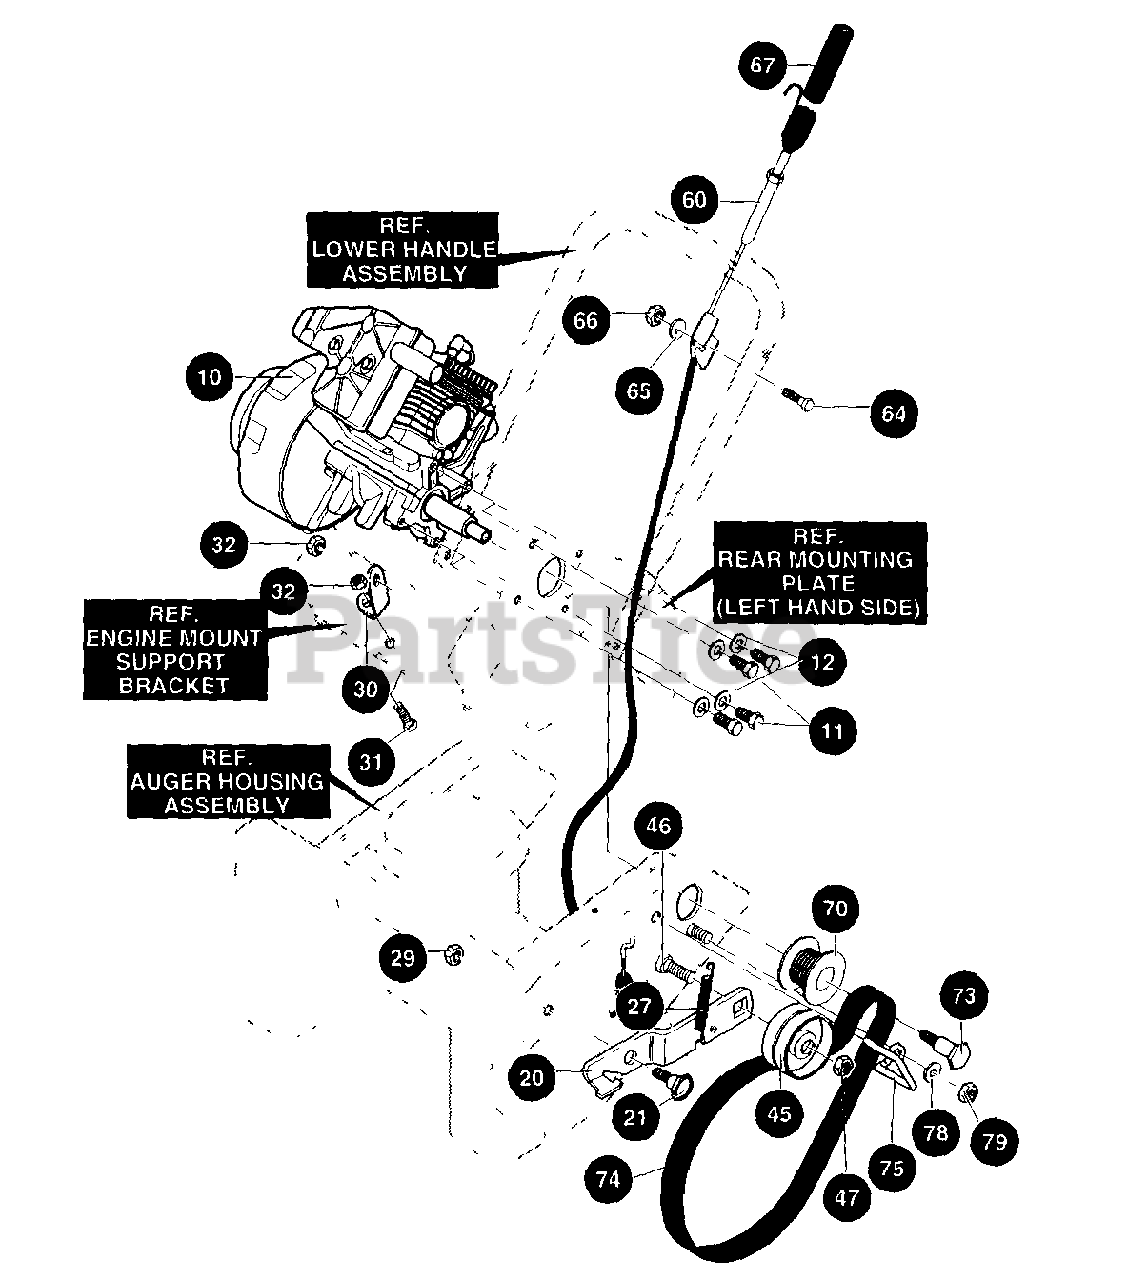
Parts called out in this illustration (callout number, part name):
10	5HP
11	SCREW, 5/16-18X.75
12	WASHER, .328X.60X.09
20	BRACKET, IDLER ARM
21	SH. BOLT 5/16-18
27	SPRING, IDLER BRAKE
29	NUT, 5/16-18 RGHXCTRLK
30	SUPPORT, ENGINE
31	SCREW 5/16-18X.50
32	NUT, 5/16-18 REGHXCTRLK
45	PULLEY, IDLER
46	CARR. BOLT, 3/8-16X1.50
47	NUT, 3/8-16 CTRLKJAM
60	CABLE, DRIVE CONTROL
64	SCREW 1/4-20X1.50
65	FLATWASHER
66	NUT, 1/4-20 RGHXCTRLK
67	COVER, CABLE SPRING
70	PULLEY, 4.5HP POLY V
73	SH. BOLT .625X.282
74	BELT, POLY
75	GUIDE, BELT
78	FLATWASHER
79	NUT, 5/16-18 REGHXCTRLK
